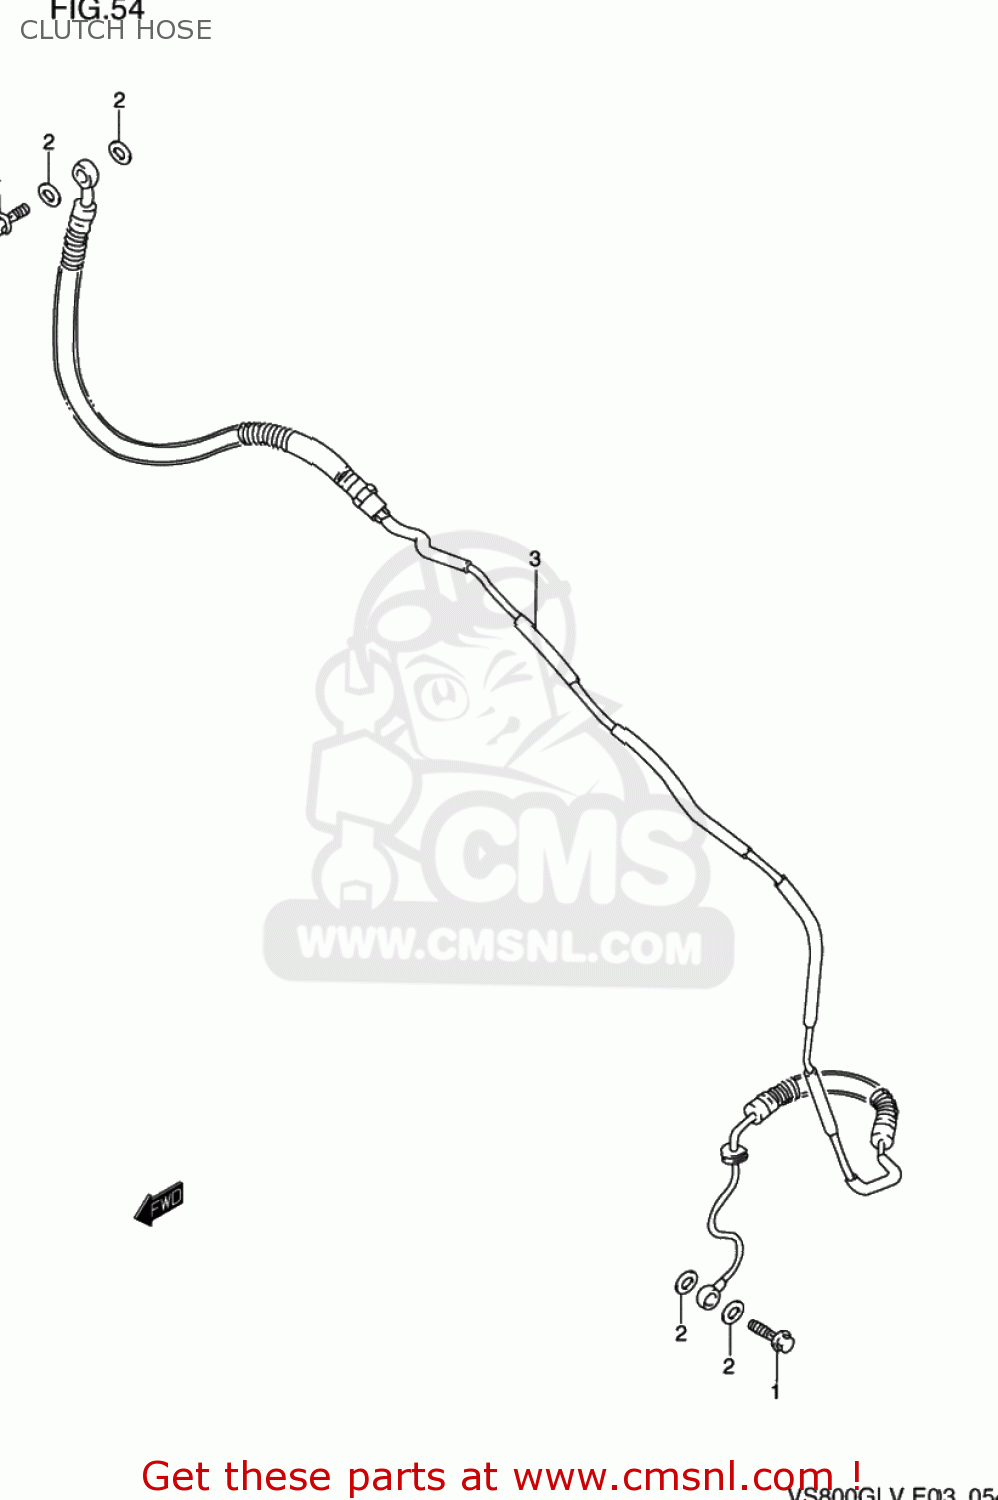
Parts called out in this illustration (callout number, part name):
1	BOLT UNION
2	WASHER(10X15X1.5)
3	HOSE ASSY,CLUTCH
